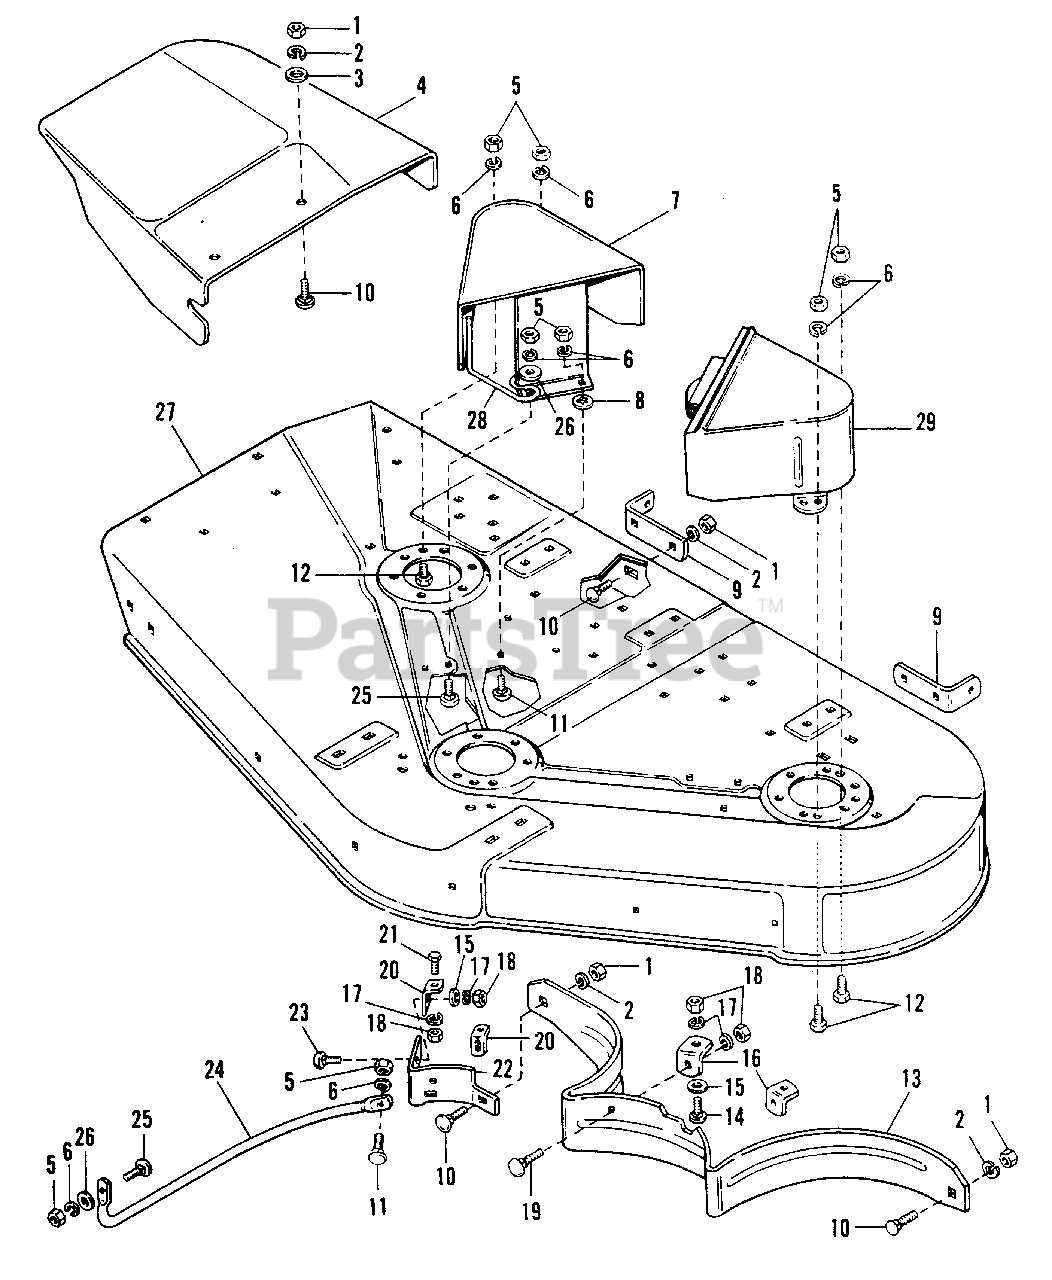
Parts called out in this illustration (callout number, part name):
1	NUT, Hex, 3/8-16
2	LOCKWASHER, 3/8
3	WASHER, Plain, 3/8
5	NUT, Hex, 5/16-18
6	LOCKWASHER, 5/16
7	ARBOR COVER ASSY.
8	PUSHNUT, 5/16
9	BRACKET, Roller Support
10	BOLT, Carriage, 3/8-16 x 3/4
11	BOLT, Carriage, 5/16-18 x 3/4
12	CAPSCREW, Hex, 5/16-18 x 3/4
13	BAFFLE
14	CAPSCREW, Hex, 1/4-20 x 3/4
15	WASHER, 1/4
16	CLIP, Baffle
17	LOCKWASHER, 1/4
18	NUT, Hex, 1/4-20
19	BOLT, Carriage, 1/4-20 x 5/8
20	CLIP GUARD & BAFFLE
21	CAPSCREW, Hex, 1/4-20 x 3/4
22	BAFFLE, Discharge
23	BOLT, Carriage, 1/4-20 x 3/4
24	GUARD, Mower Discharge
25	BOLT, Carriage, 5/16-18 x 1
26	WASHER, 11/32 x 1
27	42" ROTARY MOWER HOUSING KIT
29	ARBOR COVER ASSY.
